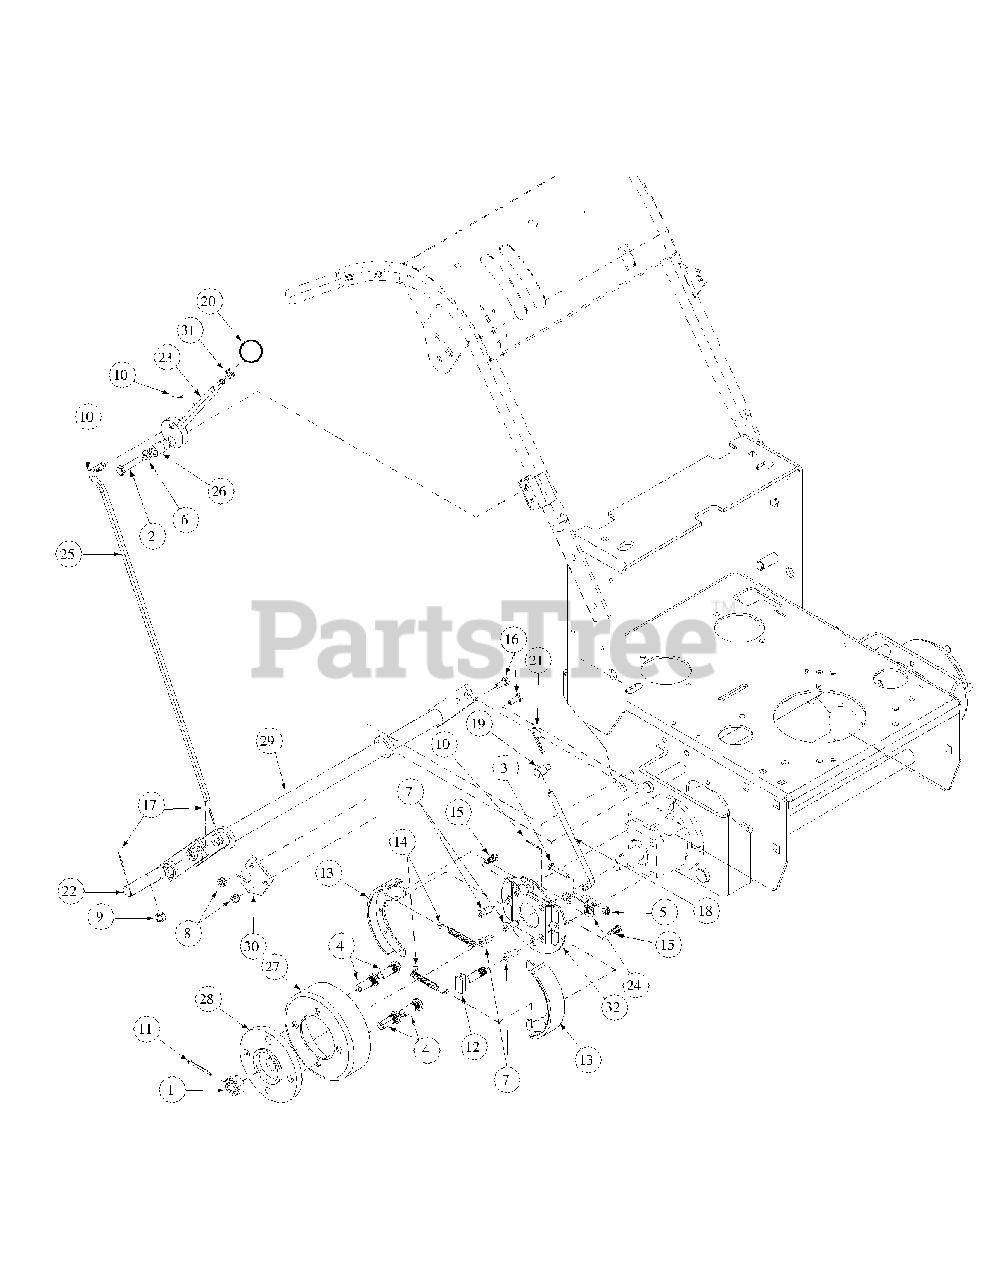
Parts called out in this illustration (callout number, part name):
1	Nut, Castle, 3/4-16
2	Capscrew, 3/8-16 x 1" Grade 5 Zinc
3	Cap Screw, 1/4-20 x 1.50, Grade 5
4	Bolt, Wheel, 1/2-20 x 1-3/8
5	Lock Nut, Nylon Insert, 1/4-20 Grade A
6	Lock Washer, 3/8 Zinc
7	Capscrew, Socket Button Hd., 3/8-16 x 3/4 Zinc
8	Nut, 5/16-18, Nylock
9	Nut, Nylon Insert, 3/8-16 Grade A
10	Cotter Pin, 3/32 x 3/4, Zinc
11	Cotter Pin, 5/32 x 1-1/2 Zinc
12	Brake Cam, Actuating
13	Brake Shoe w/Lining, 6 x 1-1/4
14	Brake Spring, Tension
15	Brake Spring, Anti-Vibration
16	Cap Screw, 5/16-18 x 3/4, Grade 5
17	Cotter Pin, 3/32 x 1, Zinc
18	Brake Rod
19	Swivel Joint
20	Knob, Red, Shift w/Insert
21	Hair Pin, 3/8"-1/2"
22	Joint, Brake Pull
23	Lever Assembly, Brake
24	Brake Clamp, Control Assembly, Hydro
25	Rod, Long Brake, Hydro WB
26	Pivot Spacer, Hydro WB
27	Brake Drum
28	Hub, Wheel Motor
29	Brake Shaft Assembly WT
30	Pivot Mount, Brake
31	Nut, 3/8-16, Jam, Grade 2
32	Brake Backing Plate
